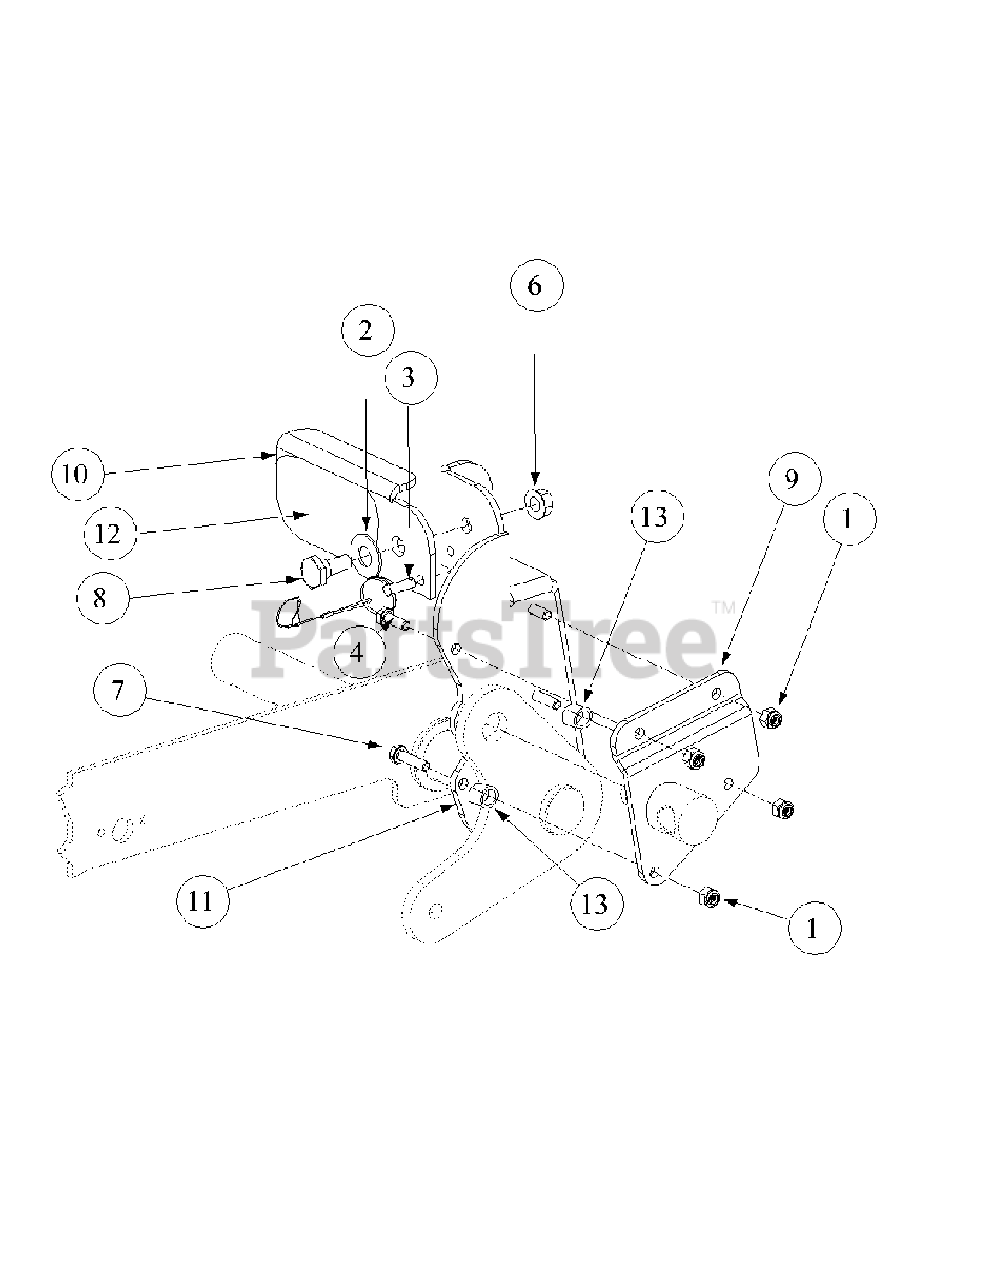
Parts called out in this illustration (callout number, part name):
1	Lock Nut, Nylon Insert, 1/4-20
2	Washer, 1/2 x 1 Shim
3	Detent Pin w/12" Lanyard
4	Hex Cap Screw, 1/4-20, .75
6	Hex Nut, Flange Lock 3/8-16
7	Hex Cap Screw, 1/4-20, 1.00
8	Shoulder Screw, .50 x .27 Lg., 3/8-16
9	Foot Lift Backup Pedal
10	Deck Foot Pedal Lift
11	Deck Foot Pedal Lift
12	Deck Foot Lift Pad
13	Turnbuckle Sleeve
